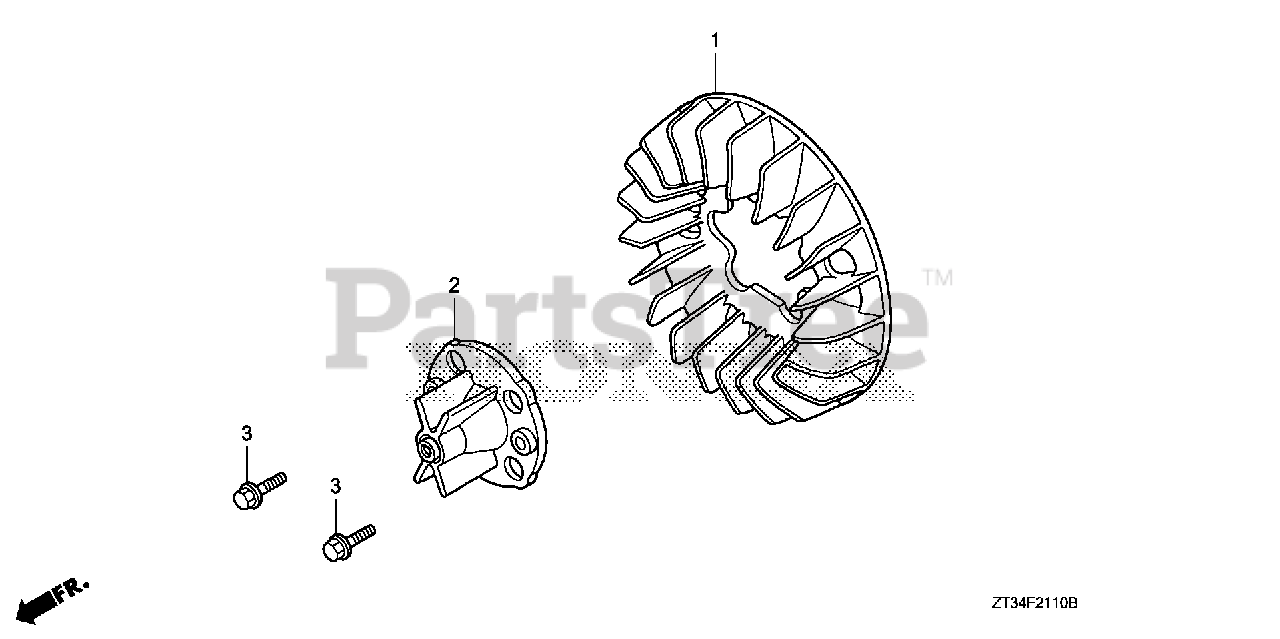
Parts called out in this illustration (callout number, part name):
1	FAN, COOLING
2	BOSS, COOLING FAN
3	BOLT, FLANGE (6X16)
